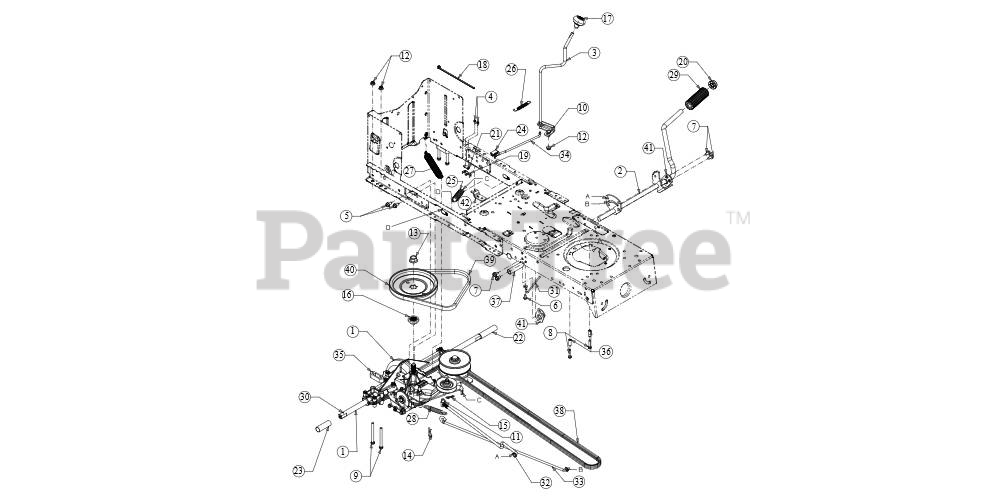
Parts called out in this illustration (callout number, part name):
1	TRANSMISSION ASSEMBLY
3	SHIFT LEVER ASSEMBLY
4	HEX SCREW WASHER HD #8-18 X 0.500
5	SCREW 5/16-18 x .750
6	SCREW 1/4-20 X.500
7	SCREW 5/16-18 X .625
8	SCREW 1/4-20 X 1.25
9	SCREW 5/16-18X3.5 GR5
10	SCREW 5/16-18 x .75 GR5
11	FERRULE 3/8-24 X .375
12	FLANGE LOCK NUT 5/16-18
13	FLANGE NUT W/HUB
14	COTTER PIN
15	BOW TIE COTTER PIN 1/4-5/16
16	PULLEY HUB
17	SHIFT KNOB
18	CABLE TIE 7",1"
19	SAFETY SPRING SWITCH
20	PUSH CAP
21	INSULATOR PLATE
22	SLEEVE
23	SLEEVE
24	SHIFT ROD BEARING
25	EXTENSION SPRING
26	EXTENSION SPRING .38 OD X 3.25 LG
27	EXTENSION SPRING .94 X 6.75
28	EXTENSION SPRING
29	FOOT PAD
31	BELT KEEPER ROD
32	VARIABLE SPEED ROD
33	BRAKE ROD
34	SHIFT ROD
35	TRANSAXLE SPACER
36	SPACER
37	SPACER-5/8 ID X 2.
38	V-BELT 70.90
39	V-BELT 5L X 35.25
40	V- PULLEY W/HUB
42	SHIFT ADJUSTMENT BRACKET
